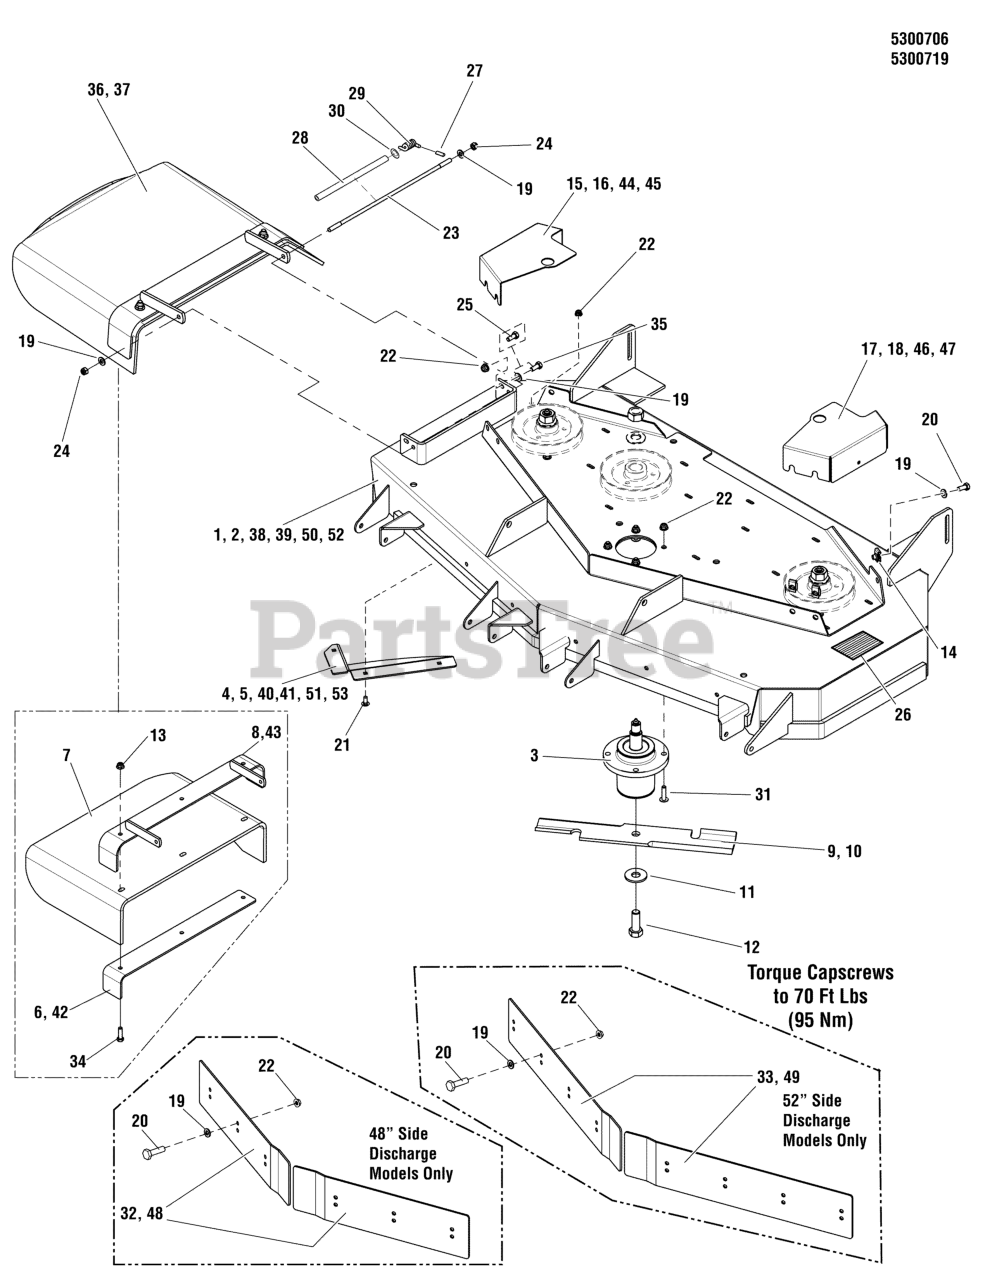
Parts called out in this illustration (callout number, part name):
1	DECK SHELL W/DECALS, 48 - IS2000YAN -RED
2	DECK SHELL W/DECALS, 52 - IS2000YAN -RED
3	ASSM, SPINDLE, LOW PROFILE
4	WELD, DISCHARGE BAFFLE, 48" - BLK
5	WELD, DISCHARGE BAFFLE, 52" - RED MODEL
6	SUPPORT, DISCHARGE CHUTE, 44/48/52 - BLK
7	CHUTE, DISCHARGE, BEND RUBBER, 44/48/52
8	WELD, MOUNT, DISCHARGE CHUTE - BLK
9	BLADE, 16.25", SAND
10	BLADE, 18", SAND
11	WASHER, 5/8" GRADE 8
12	BOLT, 5/8-11 X 1-3/4 GD8
13	NUT, 3/8-16 HEX NYLOCK FLANGE
14	BODY CLIP, 5/16-18-7GA MATERIAL
15	GUARD, 48" DECK, RH - IS2000 YANMAR -RED MODEL
16	GUARD, 52" DECK, IS2000 - RH - RED MODEL
17	GUARD, 48" DECK, LH - IS2000 YANMAR - RED MODEL
18	GUARD, 52" DECK, IS2000 - LH - RED MODEL
19	WASHER, 5/16" SAE
20	BOLT, 5/16-18 X 3/4 GD5
21	BOLT, 5/16-18 X 3/4", CARRIAGE
22	NUT, 5/16-18 HEX NYLOCK FLANGE
23	ROD, BRAKE LINKAGE
24	NUT, 5/16-18 HEX NYLON LOCK
25	BOLT, 5/16-18 X 3/4 GD5
26	SAFETY WALK, 4.00 X 7.50
27	CAP, PROTECTOR, .120 ID
28	SPACER, TORSION SPRING,9.63 LG
29	SPRING, TORSION
30	WASHER, 5/16" FENDER
31	BOLT, 5/16-18 X 1 1/4" FLANGE
32	BAFFLES. FRONT DISCHARGE, 48 YAN - RED MODEL
33	BAFFLES. FRONT DISCHARGE, 52 YAN - BLK
34	BOLT, 3/8-16 X 1-1/2" GD5 CZ
35	BOLT, 5/16-18 X 1-1/4" GD5 YZ
36	KIT, DISCHARGE CHUTE, 44/48/52
37	KIT, DISCHARGE CHUTE, 44/48/52
38	DECK SHELL W/DECALS, 48 - IS2000YAN -ORG
39	DECK SHELL W/DECALS, 52 - IS2000YAN -ORG
40	WELD, DISCHARGE BAFFLE, 48" - ORANGE MODEL
41	WELD, DISCHARGE BAFFLE, 52" - ORANGE MODEL
42	SUPPORT, DISCHARGE CHUTE, 44/48/52 - BLK
43	WELD, MOUNT, DISCHARGE CHUTE - BLK
44	GUARD, 48" DECK, RH - IS2000 YANMAR - ORANGE MODEL
45	GUARD, 52" DECK, IS2000 - RH - ORANGE MODEL
46	GUARD, 48" DECK, LH - IS2000 YANMAR - ORANGE MODEL
47	GUARD, 52" DECK, IS2000 - LH - ORANGE MODEL
48	BAFFLES. FRONT DISCHARGE, 48 YAN - ORANGE MODEL
49	BAFFLES. FRONT DISCHARGE, 52 YAN - BLK
50	DECK SHELL W/ DECALS, 52, IS2000YAN - RED MODEL
51	PLATE, DEFLECTOR, 52" - BLK
52	DECK SHELL W/ DECALS, 52, IS2000YAN - ORANGE MODEL
53	PLATE, DEFLECTOR, 52" - BLK
